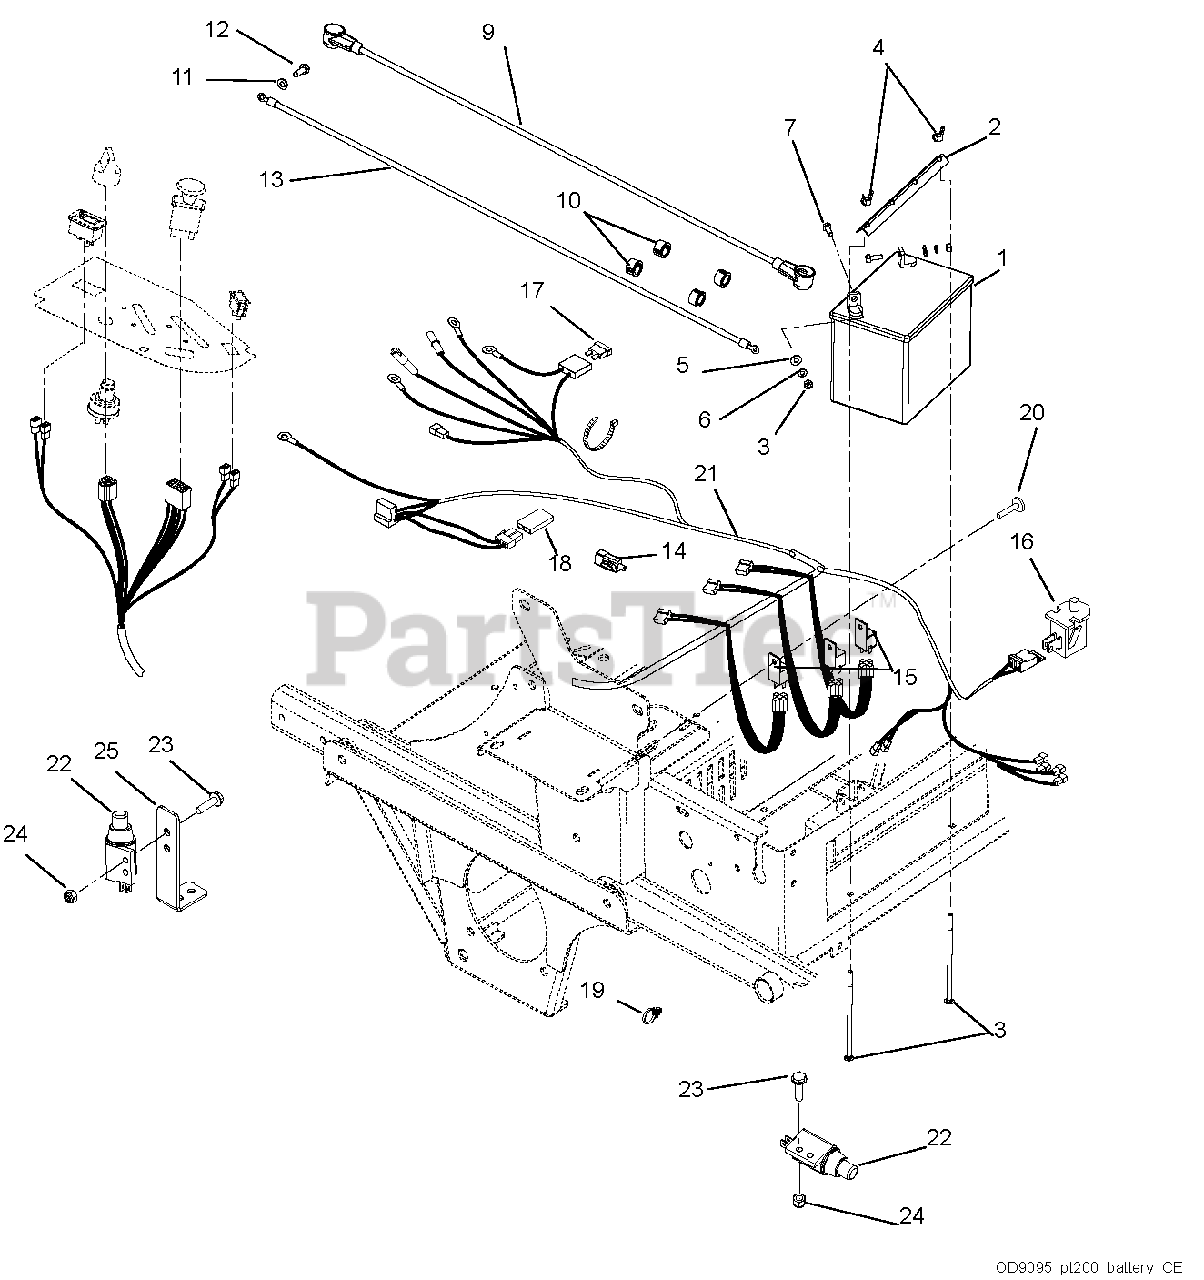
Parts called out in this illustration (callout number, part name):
1	Battery, SMF U1-9U1L/U1H
2	Hold Down
3	Bolt, Round Head Square Neck .25-20 x 7.50
4	Nut, Locking Wing .250-20
5	Washer, Flat-Steel .281 x .62 x .065
6	Washer, Locking .25 x .062 Regular
7	Bolt, Hex .25-20 x .75 Grade 5
8	Nut, Hex .25-20
9	Cable, POS Battery w/Boots 6 x 35
10	Bushing, Panel Snap .687 x .875 x .56
11	Washer, Locking .31 x .078 Regular
12	Bolt, Hex M8-1.25 x 20
13	Cable, Negative Battery 35.0"
14	Switch, Snap-In - N.O./N.O.
15	Relay (Included with Harness)
16	Switch, Snap Mounting
17	Fuse, 30 Amp (Included with Harness)
18	Diode, Connector Shell
19	Cable Tie with TREE (.25 HOLE)
20	Rivet, .25 Nylon Panel
21	Harness, Vertical A/C Wiring
22	Switch, Single Pole (N.O.) with Cover
23	Screw, Machine 10-24 x .75 Hex Washer Head
24	Nut, Locking Nylon 10-24 with Insert
25	Mount, Switch PT200 CE
